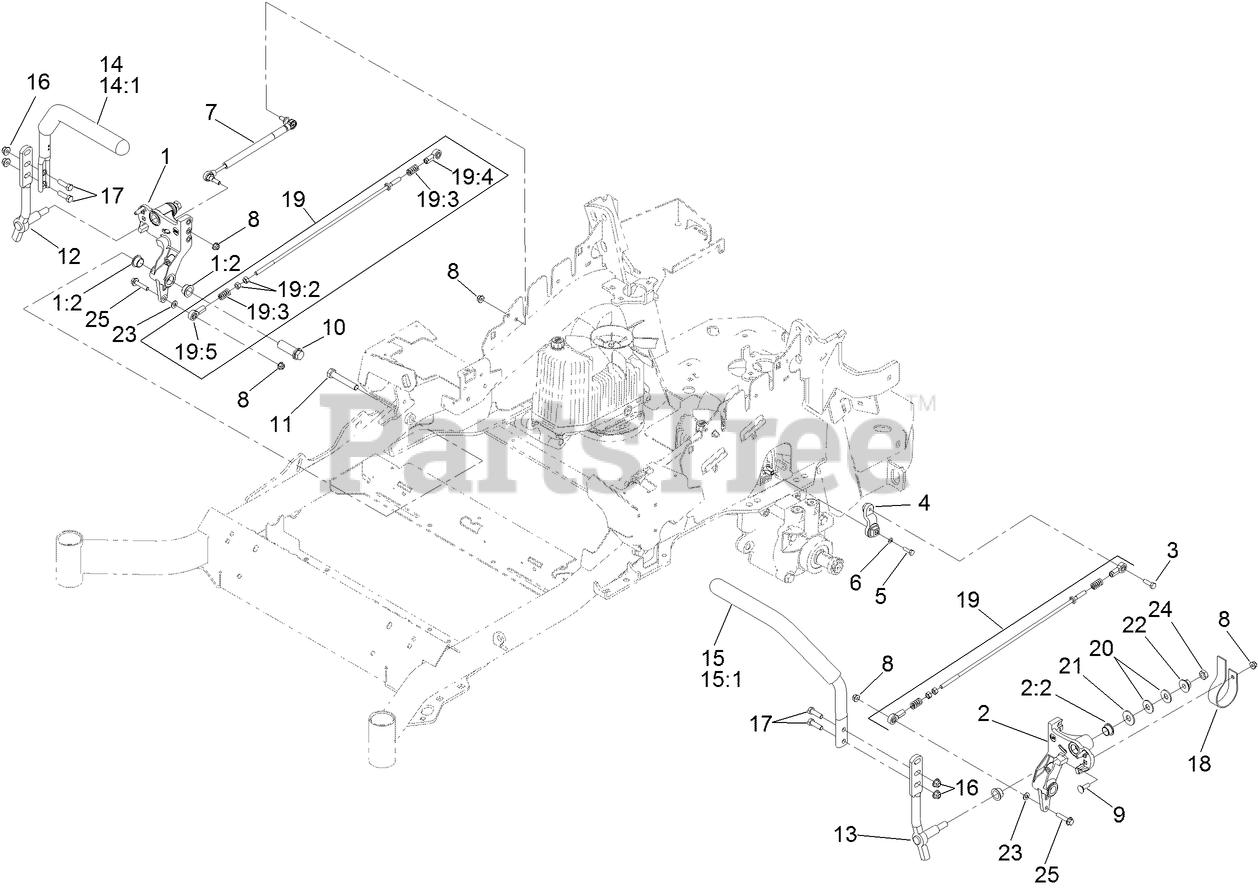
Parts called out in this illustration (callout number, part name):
1	RH MOTION CONTROL AND BUSHING ASM
1:2	BUSHING-FLANGE
2	LH MOTION CONTROL AND BUSHING ASM
2:2	BUSHING-FLANGE
3	SCREW-HH, THREAD LOCKING
4	ARM-CONTROL, PUMP
5	SCREW-HH
6	WASHER-SPRING
7	DAMPER-CONTROL, MOTION
8	NUT-HF, NI
9	BOLT-CARR
10	HUB-THREADED
11	SCREW-HH
12	LEVER-CONTROL MOTION, RH
13	LEVER-CONTROL MOTION, LH
14	RH STEERING HANDLE ASM
14:1	GRIP-CONTROL, LEVER
15	LH STEERING HANDLE ASM
15:1	GRIP-CONTROL, LEVER
16	NUT-HF, NI
17	SCREW-HH
18	SPRING-LEAF
19	FRONT PUMP LINKAGE ASM
19:2	NUT-HEX
19:3	SPRING-COMPRESSION
19:4	BALLJOINT-LH
19:5	BALLJOINT-RH
20	WASHER-SPRING
21	WASHER-FLAT
22	NUT-HF
23	WASHER-PLAIN
24	NUT-JAM
25	SCREW-HHF
